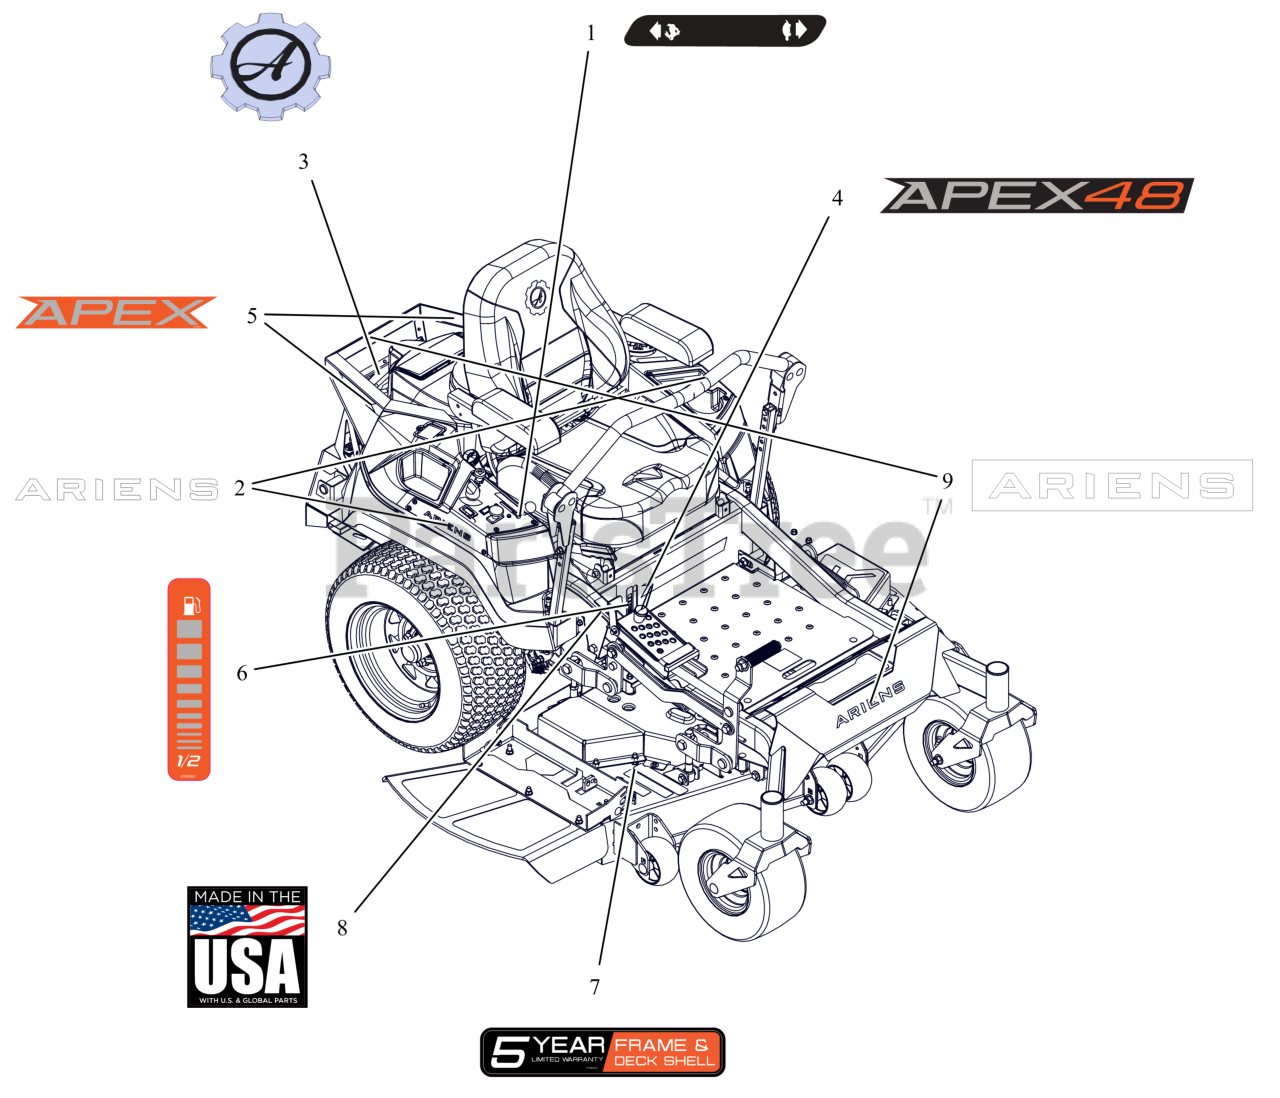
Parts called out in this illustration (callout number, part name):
1	DECAL, DASH DECAL
2	DECAL, ARIENS (6.50")
3	DECAL, ARIENS-GEAR BADGE -THK
4	DECAL, 48" APEX KICKPLATE
5	DECAL, APEX FENDER
6	DECAL, ARIENS FUEL LEVEL
7	DECAL, DECK 5 YEAR-ARIENS
8	DECAL, MADE IN USA
9	DECAL - ARIENS 9.625"
